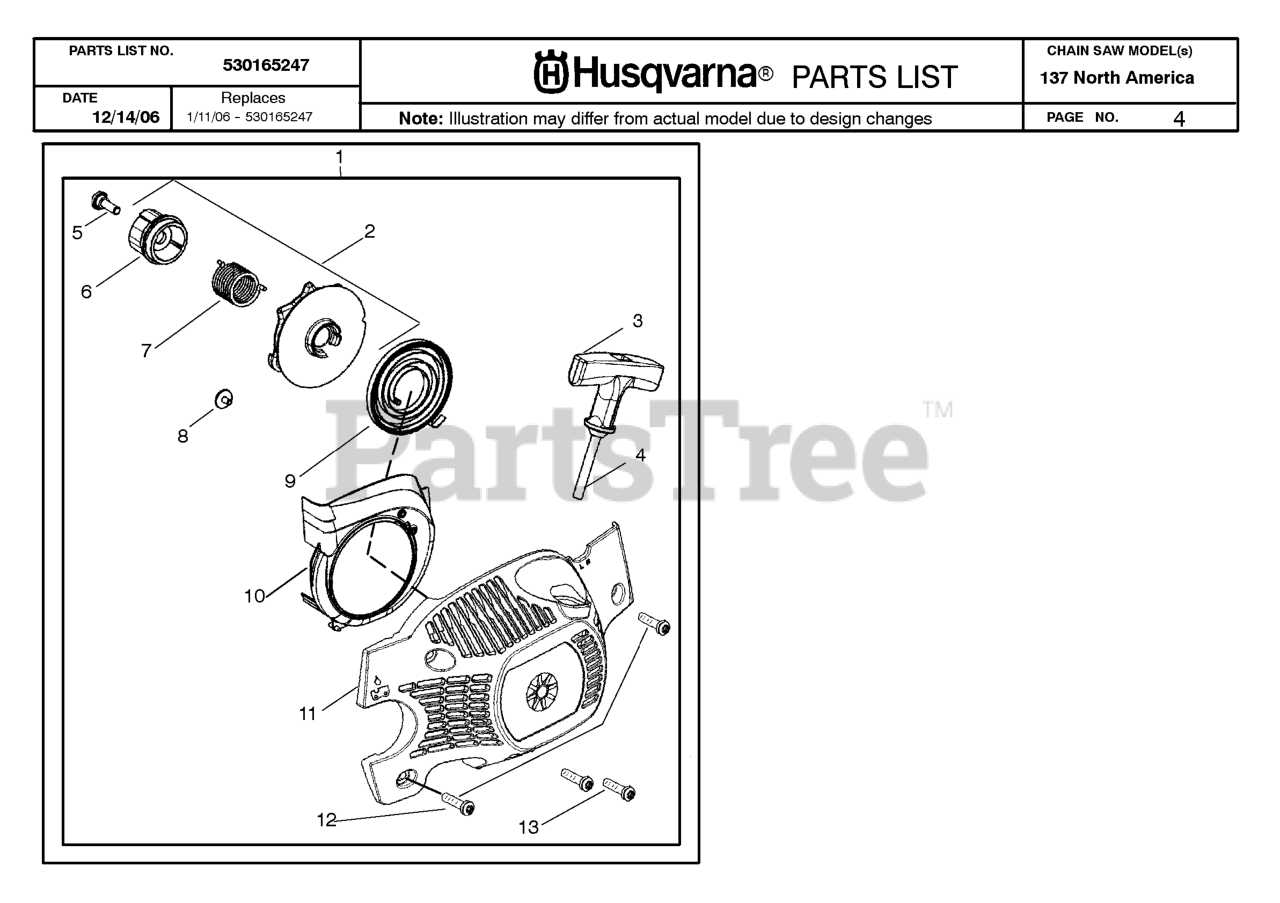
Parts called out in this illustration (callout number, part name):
1	KIT FAN HSG & STARTER EPS
2	KIT EPS STARTER
3	STARTER HANDLE GRAY
5	SCREW SHOULDER
6	HUB STARTER EPS
7	SPRING EPS
9	SPRING STARTER
10	BAFFLE AIR
11	HOUSING FAN W/ EYELET
13	SCREW,STRTR CVR 36/41
